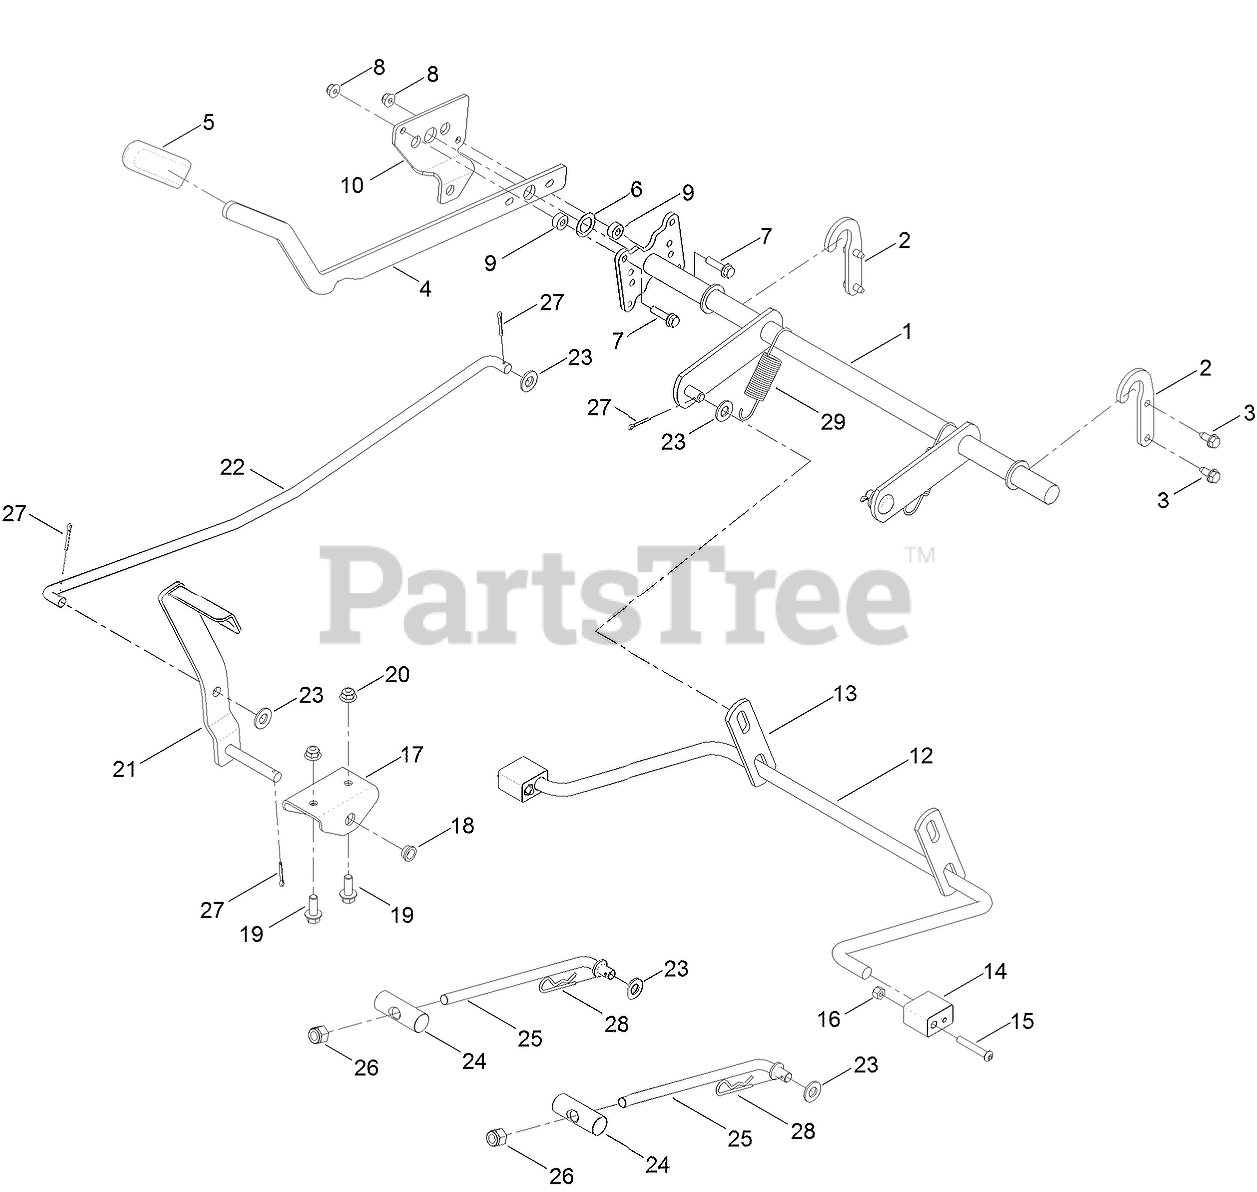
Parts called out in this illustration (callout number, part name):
1	DECK LIFT ASM
2	BRACKET-LIFT
3	SCREW-HWHTF
4	LEVER-LIFT
5	GRIP-LEVER
6	WASHER-THRUST
7	SCREW-HHF
8	NUT-HF, NI
9	SPACER
10	PLATE-FOOTLIFT
12	ARM-LIFT, REAR (WIDE)
13	LINK-LIFT
14	BLOCK-PIVOT
15	SCREW-HSBH
16	NUT-LOCK, NI
17	BRACKET-FOOTLIFT
18	BUSHING-FLANGE
19	SCREW-HHF
20	NUT-HF, NI
21	PEDAL ASM
22	ROD-FOOTLIFT
23	WASHER-FLAT
24	PIN-PIVOT
25	ROD-MOUNT, DECK
26	NUT-HEX
27	PIN-COTTER
28	PIN-COTTER
29	SPRING, EXTENSION
